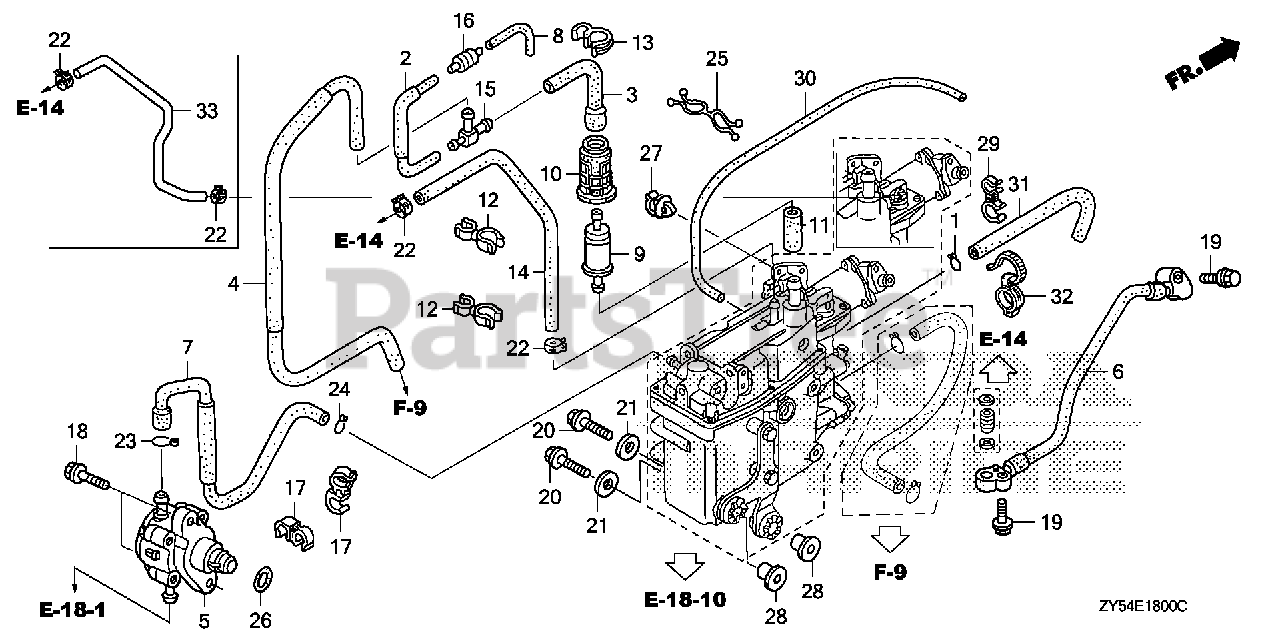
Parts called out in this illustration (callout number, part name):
1	CLIP, TUBE
2	TUBE C, AIR VENT
3	TUBE B, AIR VENT
4	TUBE, AIR VENT
5	PUMP ASSY., FUEL (MSDS)
6	HOSE, FUEL
7	TUBE B, FUEL
8	TUBE D, FUEL
9	FILTER, FUEL PUMP
10	SUSPENSION, STRAINER
11	TUBE B, FUEL
12	CLAMP, HOSE
13	CLAMP, PIPE
14	HOSE, PRESSURE REGULATOR RETURN
16	VALVE, CHECK
17	CLIP, SENSOR HOSE
18	BOLT, FLANGE (6X27)
19	BOLT, FLANGE (6X25)
20	BOLT, FLANGE (8X35)
20	BOLT-WASHER (8X35)
21	WASHER, PLAIN (8MM)
22	CLAMP, TUBE (D10.7)
23	CLIP, TUBE (B1 14.5)
24	CLIP, TUBE (B12)
25	CLIP, FUEL HOSE
26	O-RING (33.2X2.4) (NOK)
27	CLIP, HARNESS
28	COLLAR (8.5X14.5)
29	CLAMP, PURGE HOSE (NOT AVAILABLE)
30	BULK HOSE, FUEL (3.5X3000) (3.5X430)
31	BULK HOSE, VACUUM (7X3000) (7X400)
32	CLIP, TUBE (135MM) (BLACK)
